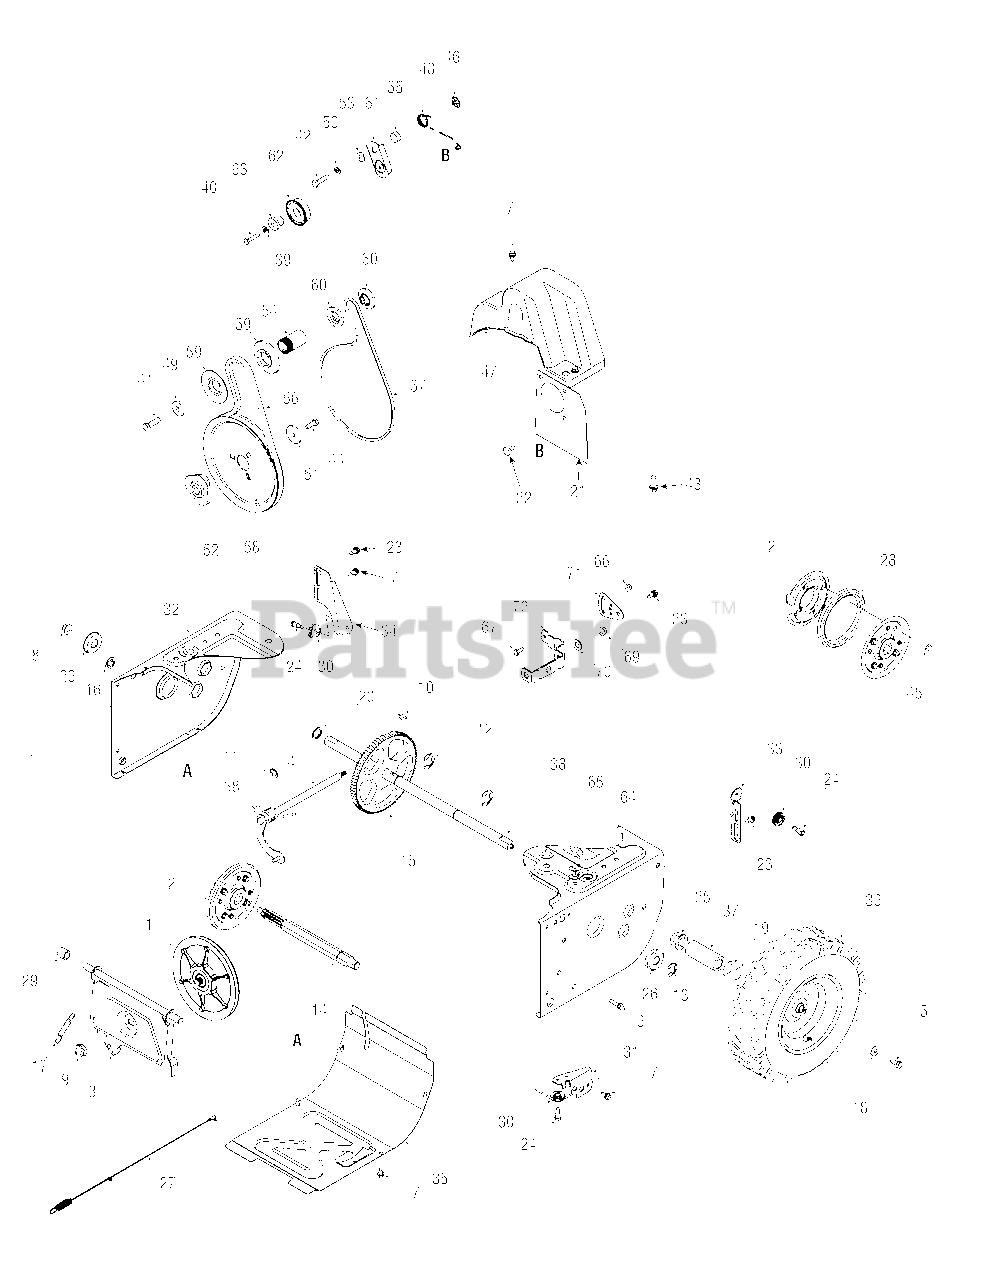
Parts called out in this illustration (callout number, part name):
1	Disc Assembly, Friction Wheel
2	Friction Wheel Assembly, 5.5 OD
3	Support Bracket, Friction Wheel
4	Shift Assembly, Rod
5	Hex Screw, 5/16-24, .750, Gr5
6	Screw, 1/4-20, 1.000
7	Screw, 1/4-20 x .625
8	Nut, Flange Lock, 3/8-16, Nylon
9	Nut, Flange, 5/8-18
10	Key, Hi Pro, 3/16 x 3/4 Dia.
11	E-ring, .500 Dia.
12	E-ring, Retaining, .875 Dia.
13	E-ring, .750 Dia.
14	Hex Shaft, .8125, 7-Tooth
15	Gear, 80-Tooth
16	Speed Nut, .500
17	Extension Spring
18	Washer, Bell, .340 x .872 x .060
19	Washer, Flat, .793 x 1.24 x .060
20	Washer, Flat, .75 x 1.00 x .060
21	Plate, Cover
22	Shoulder Screw
23	Screw, Shoulder, .37 x .105, 1/4-20
24	Screw, 1/4-28, .375
25	Bearing, Hex Flange x .75 ID
26	Bearing, Ball, 17 x 40 x 12
27	Clutch Cable, Wheel, 44.95"
28	Rubber, Friction Wheel, 5.5 OD
29	Spacer, .508 ID x .75 OD x .68
30	Roller, Cable
31	Front Guide Bracket, Auger Cable
32	Frame
33	Guide Bracket, Auger Cable
34	Guide Bracket, Drive Cable
35	Cover, Frame
36	LH Wheel Assembly
36	RH Wheel Assembly
37	Spacer, 1.25 x .75 x 3.0
38	Axle, .75 x 22"
39	Washer, Lock, 1/4
40	Hex Screw, 1/4-20, 1.25, Gr5
41	Hex Screw, 3/8-24, 1.25, Gr8
42	Hex Screw, 5/16-24, 1.25, Gr5
43	Screw, Sems, 3/8-16, 1.00
44	Hex Screw, 5/16-24, .875, Gr8
45	Screw, 1/4-20 x .625
46	Nut, Push-on, .25 Dia.
47	Cover, Belt
48	Spring, Torsion, .850 ID x .354
49	Washer, Flat, .406 x 1.25 x .157
50	Washer, Lock .3125
51	Washer, Flat, .34 x 1.50 x .150
52	Pulley, Adapter, .75 Dia.
53	Spacer, Shoulder, .317 x .50 x .102
54	Spacer, .875 ID x 1.185 OD
55	Spacer, .340 x .750 x .360
56	Belt, Auger Drive
57	Belt, Wheel Drive
58	Pulley, Auger Drive, 8.1 x .5
59	Pulley, Half, V x 2.600 OD
60	Pulley, Half, 3/8-V x 1.7160 OD
61	Idler Bracket, Wheel Drive
62	Idler Pulley Assembly
63	Spacer, Shoulder, .26 x .79 x .538
64	Plug, 3/8 ID
65	Plug, 1/2 ID
66	Nut, Flange Lock, 1/4-20, Nylon
67	Hex Screw, 1/4-20, .620, Gr5
68	Spring, Torsion, .750 ID x .968
69	Nut, Flange Lock, 5/16-18, Nylon
70	Wash., Flat, .469 x .875 x .105
71	Pivot Bracket, Speed Selector
72	Shift Bracket, Speed Selector
